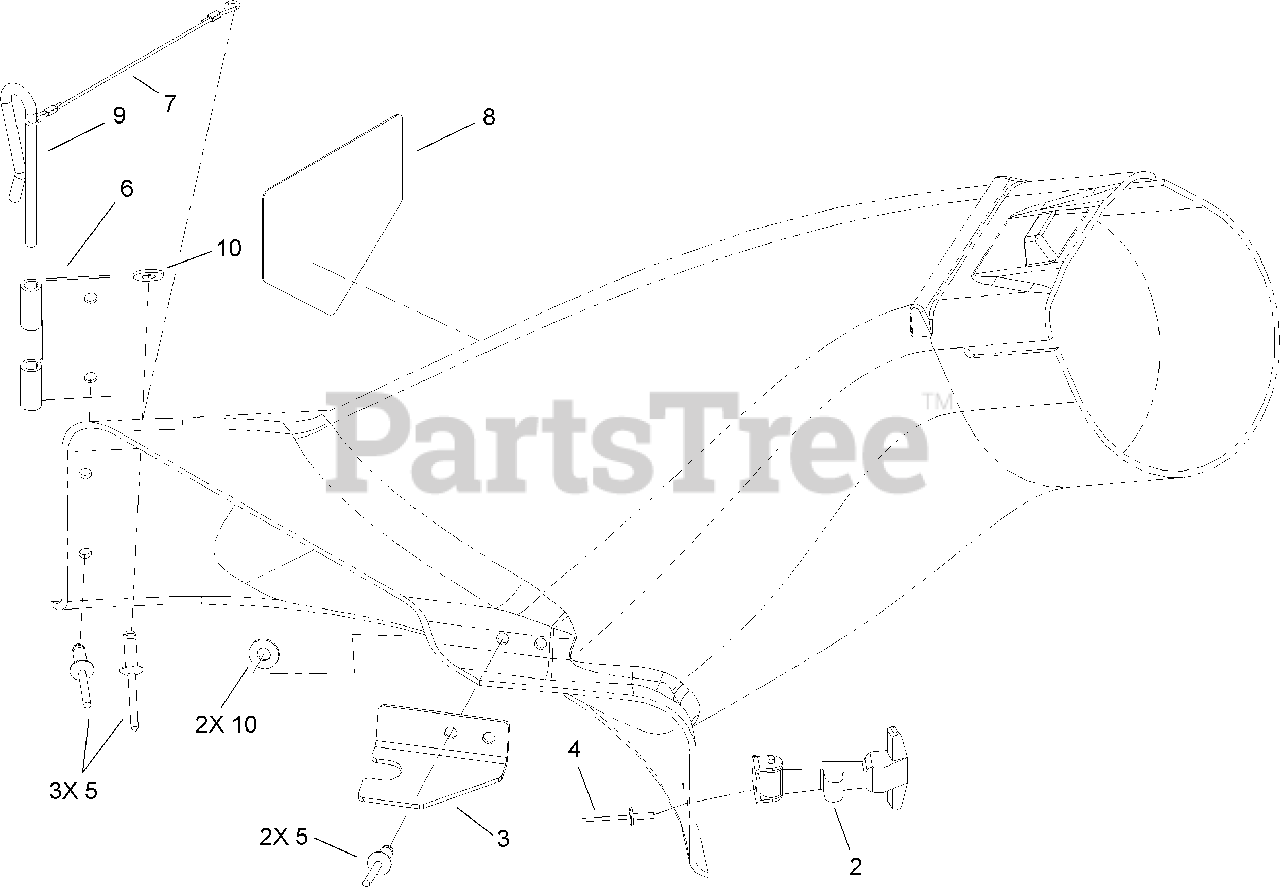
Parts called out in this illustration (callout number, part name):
2	HANDLE ASM
3	LATCH-ELBOW, BAGGER
4	RIVET-POP
6	BRACKET-MOUNTING, CHUTE
8	DECAL-DANGER
9	PIN-LOCKING, CHUTE
10	WASHER-FLAT
